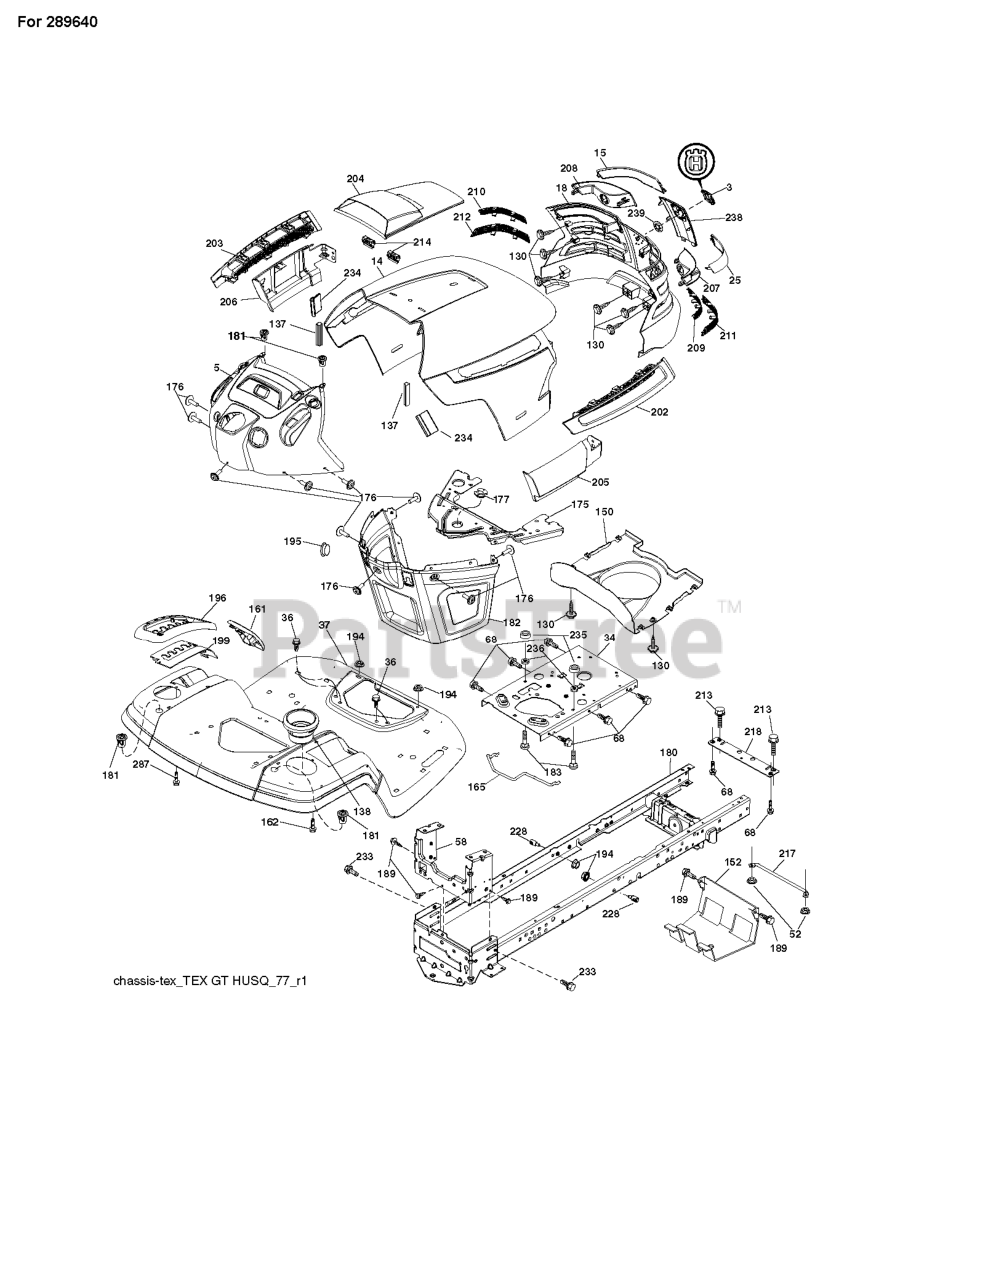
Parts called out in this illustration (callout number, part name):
3	RP LOGO
14	HOOD
15	LENS.LH.TEX.GT.HUSQ.CL
18	GRILL.ASM.HUSQ.TG/CRD.W/TRIM
25	LENS.RH.TEX.GT.HUSQ.CL
34	PLATE.ENGINE.WELDED.CHASSIS
36	SCREW 5/16"
37	FENDER.ERGO.LT.W/CPH.W/FW.ORNG
52	LOCKNUT
58	DRAWBAR UPPER 2PC SMALL FENDER
68	Screw 5/16-18 x 1/2 Hex, Self Tapping 5/16-18 x 1/2
130	SCREW.#10 X 0.750.BOS
137	BUMPER DASH
138	HOLDER.CUP.LT.GREY
138	CUPHOLDER.TL.TEX.418
150	AIR.DUCT.HOOD.TEX.GT.HUSQ
152	SHIELD.BROWNING.W/TEX
161	WINDOW.FUEL.LT.HUSQ.TEX.498
161	WINDOW FUEL
162	SCREW.HI-LO.CONSOLE
165	SUPPORT.TANK.REAR.W/TEX
175	PLATE.CROSSMEMBER.HUSQ
176	SCREW.#10-24X5/8.RN.QU
177	BUSHING, STEERING
180	CHASS.WLDMNT.TL.12GA/2P.48/54
181	BUSHING.MNT.FEND.CRGO.TEX.49
181	BUSHING.MNT.FEND.CRGO.
182	DASH.LOWER.COMMON.12V.ADAPTOR
183	BOLT.5/16-18X1-1/4 FULL THD
189	SCREW
194	NUT LOCK HEX FLANGE 5/16-18
195	PLUG.HOLE.DASH.LOWER.12V.BLK
196	RP CONSOLE.ASM.DECKLFT.GR/RBT.
199	PLATE.DECK.LIFT.HUSQ.LT
202	VENT.SIDE.HOOD.HUSQ.RH.GREY
203	VENT.SIDE.HOOD.HUSQ.LH.GRAY
204	HOOD VENT
205	SKIRT.HOOD.SIDE.HUSQ.RH.GREY
206	SKIRT.HOOD.SIDE.HUSQ.LH.GREY
207	BEZEL.RH.TEX.GT.HUSQ
208	BEZEL.LH.TEX.GT.HUSQ
209	INSERT.HEX.GRILL.HUSQ.GREY
210	INSERT.HEX.GRILL.HUSQ.
211	INSERT.HEX.GRILL.HUSQ.
212	INSERT.HEX.GRILL.HUSQ.
213	BOLT
214	CLIP.RETAINER.TINNER.
217	ROD.PIVOT.HOOD
218	X-PIECE.HOOD.STOP.NON/
228	STUD.FASTNER.W/ANTI-ROTATE
233	BOLT.SHOULDER
234	BUMPER.HOOD.TEX.HUSQVARNA
235	SPACER FENDER
236	NUT.CENTERLOCK.5/16-
238	TRIM.HUSQ.TG/CRD.SERVICE
239	NUT PUSH M
287	SCREW 1/4X20
